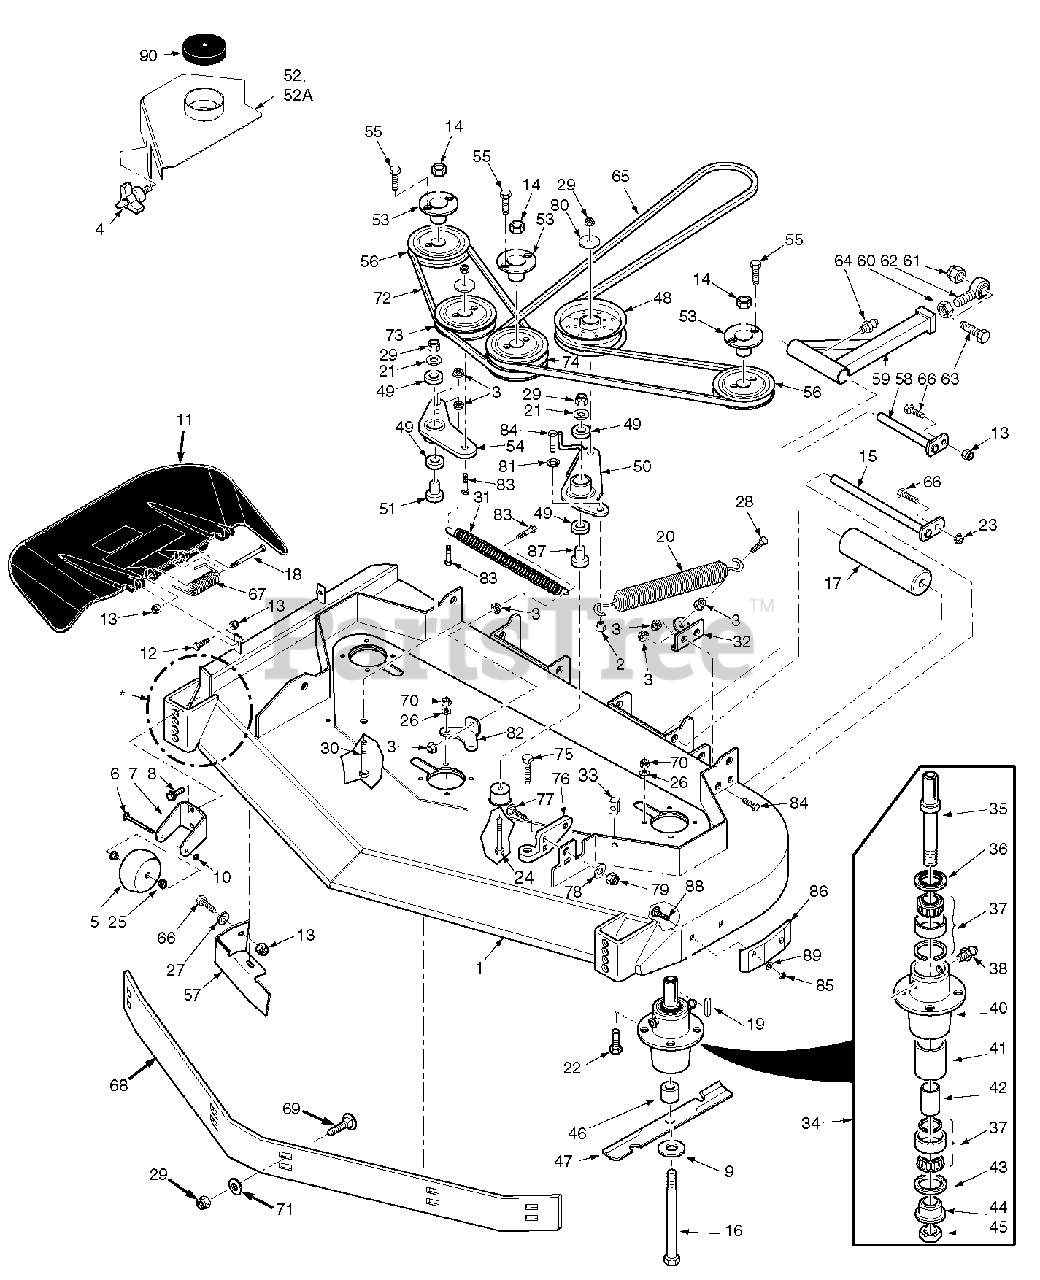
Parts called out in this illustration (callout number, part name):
1	Cutter Deck Velocity Plus
2	Boss, Spring Anchor
3	Nut, 3/8-16 Serrated Flange
4	Wing Nut, 3/8-16
5	Anti-Scalp Wheel
6	Bolt, Carriage 3/8-16 x 4"
7	Bracket, Anti-Scalp Wheel
8	Bolt, Serrated Flange 3/8-16 x 1"
9	Flatwasher, 5/8" Hardened
10	Locknut, 3/8-16 Center Lock
11	Discharge Chute Assy.
12	Bolt, Hex Head 5/16-18 x 1-1/2", Rear
12	Bolt, Hex Head 5/16-18 x 1-3/4", Front
13	Nut, Elastic Stop 5/16-18
14	Nut, 5/8-11 UNC
15	Shaft, Roller
16	Bolt, Hex Head 5/8-11 x 9-1/2"
17	Roller, Rear
18	Bolt, Hex Head 5/16-18 x 4-3/4"
19	Key, 1/4 x 1/4 x 2"
20	Spring, Idler LH
21	Flatwasher, 3/8"
22	Bolt, Hex Head 5/16-18 x 1-3/4" Gr. 8
23	Nut, Serrated Flange 5/16-18
24	Bolt, Hex Head 3/8-16 x 3-3/4"
25	Bushing, .376 ID Oilite
26	Lockwasher 5/16"
27	Flatwasher 5/16"
28	Bolt, Hex Head 3/8-16 x 1-1/2" Gr. 8
29	Nut, Elastic Stop 3/8-16
30	Bolt, Hex Head 3/8-16 x 2-1/2"
31	Spring, Idler RH
32	Bracket, Spring Anchor LH 48V
32	Bracket, Spring Anchor LH 52V
33	U-Nut, 3/8-16
34	Spindle Assembly
35	Shaft, Spindle
36	Seal Upper
37	Bearing Assembly
38	Grease Fitting
39	Valve, Grease Relief
40	Housing, Spindle
41	Spacer, Outside
42	Spacer, Inside
43	Seal, Lower
44	Bushing, Bottom
45	Nut, Special 1-1/16 - 18
46	Spacer, Spindle
47	Cutter Blade 16.5"
47	Cutter Blade 18"
48	Pulley, Idler 5" Dia.
49	Bearing
50	Idler Arm Assy.
51	Idler Pivot
52	Belt Cover Weldment RH
52	Belt Cover Weldment LH
52A	Belt Cover Weldment RH
52A	Belt Cover Weldment LH
53	Hub, Tapered 1-1/8" Bore
54	Idler Arm
55	Bolt, Hex Head 1/4-20 x 1"
56	Pulley 4.75"
56	Pulley 5.35"
57	Turbo Baffle, Bolt On
58	Push Arm Shaft
59	Push Arm
60	Nut, 5/8-18 UNF
61	Nut, Elastic Stop 5/8-11
62	Rod End, 5/8 Male RH Thread
63	Bolt, Hex Head 5/8-11 x 4-1/2"
64	Grease Fitting, 90 Degree
65	Belt, Cutter Deck Drive (48V)
65	Belt, Cutter Deck Drive (52V)
66	Bolt, Hex Head 5/16-18 x 1"
67	Spring, Discharge Chute
68	Baffle Custom-Cut, 48V (7-Position)
68	Baffle Custom-Cut, 52V (7-Position)
69	Bolt, Carriage 3/8-16 x 1"
70	Nut, Elastic Stop 5/16-18
71	Flatwasher 3/8"
72	Belt, RH Cutter Deck
73	Pulley, Idler 5" Dia.
74	Pulley, Double Groove
75	Bolt, Special
76	Lever Assy., Deck Level
77	Bolt, Carriage 7/16-14 x 1-1/4"
78	Flatwasher, 7/16-.500 x 1.25 x .083"
79	Nut, Elastic Stop 7/16-14
80	Dust Shield
81	Lockwasher 3/8"
82	Bracket, Spring Anchor RH
83	Bolt, Hex Head 3/8-16 x 1-1/2" Gr. 8
84	Bolt, Hex Head 3/8-16 x 1"
85	Nut, Center Lock 5/16-18
86	Wear Pad
87	Idler Pivot
88	Bolt, Carriage 5/16-18 x 3/4"
89	Flatwasher, 5/16"
90	Cap, Spindle
